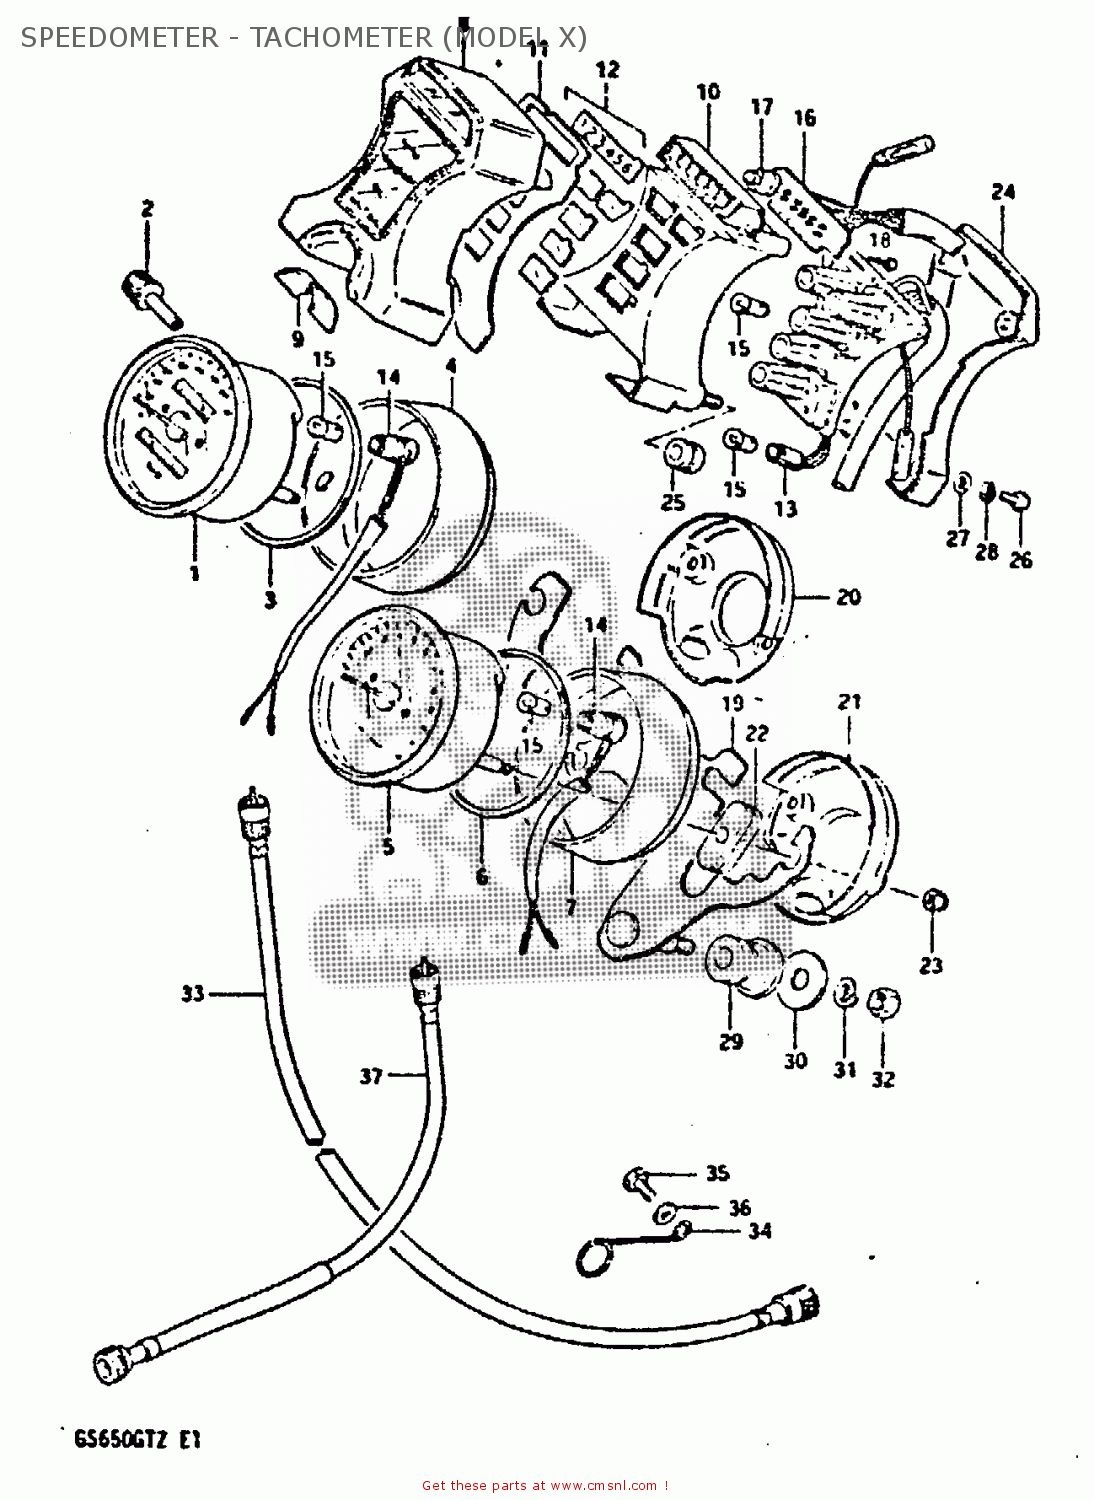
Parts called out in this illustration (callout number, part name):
1	SPEEDOMETER
2	KNOB,TRIP METER
3	CUSHION,SPEEDOMETER
4	COVER,SPEEDOMETER
5	TACHOMETER
6	CUSHION,SPEEDOMETER
7	COVER,TACHOMETER
8	CASE,PILOT BULB
9	PAD
10	CASE,PILOT BULB,INNER
11	PLATE,PILOT BOX
12	LENS SET,PILOT LAMP
13	SOCKET
14	SOCKET,METER
15	BULB(12V3.4W,STANLEY,A72A)
16	SOCKET,GEAR INDICATOR
17	BULB(14V1.12W)
18	SCREW,GEAR INDICATOR
19	BRACKET,COMBINATION METER
20	COVER,SPEEDOMETER,UNDER
21	COVER,TACHOMETER,UNDER
22	CUSHION,METER
23	NUT
24	COVER,PILOT BOX,UNDER
25	CUSHION
26	SCREW
27	WASHER
28	LOCK WASHER
29	CUSHION,METER BRACKET
30	WASHER (8.5X29X1.6)
31	LOCK WASHER
32	NUT
33	CABLE ASSEMBLY,SPEEDOMETER
34	CLAMP,SPEEDOMETER CABLE
35	BOLT, UPPER
36	WASHER
37	CABLE ASSEMBLY,TACHOMETER
